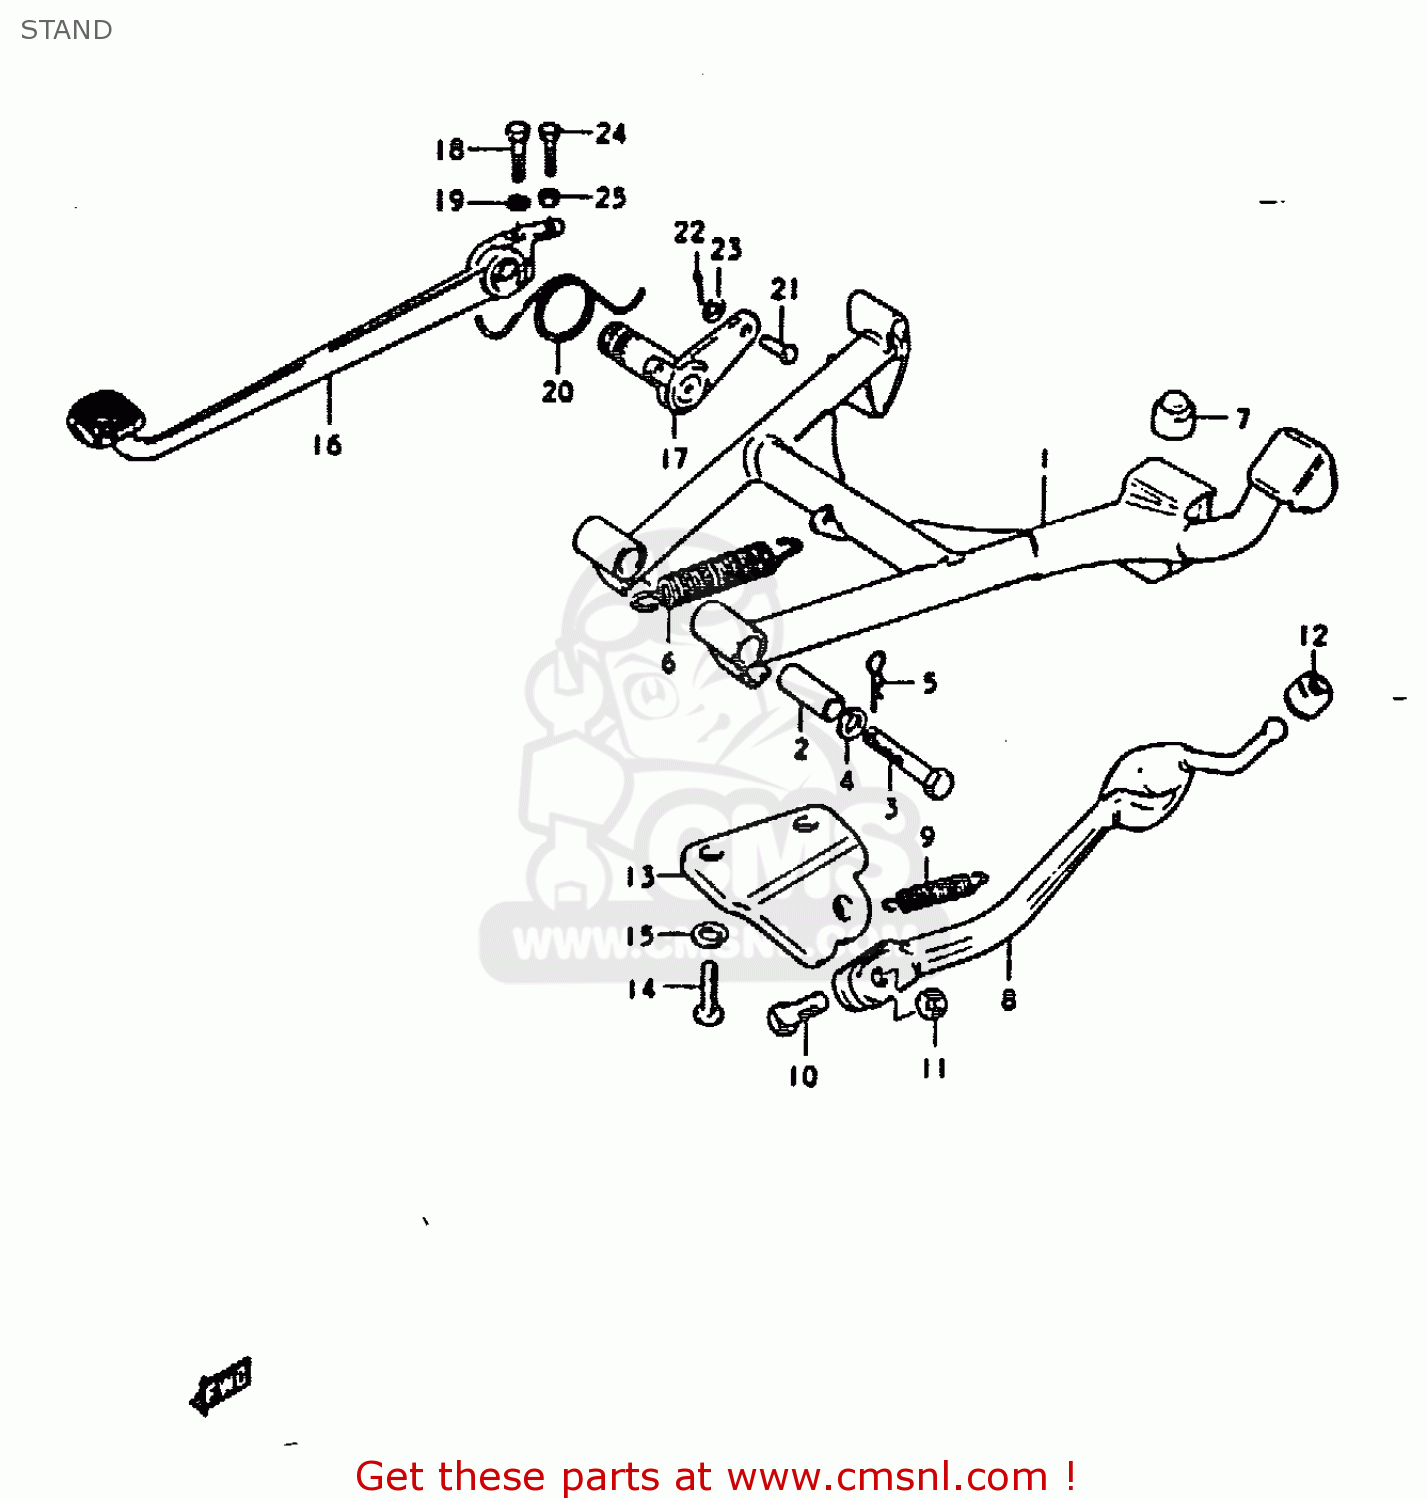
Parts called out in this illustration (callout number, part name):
1	STAND,CENTER
2	SPACER(10X16X38.8)
3	BOLT
4	LOCK WASHER
5	CLIP
6	SPRING
7	CUSHION
8	STAND,PROP
9	SPRING
10	BOLT(10X30)
11	NUT
12	CUSHION
13	BRACKET,SIDE STAND
14	BOLT
15	LOCK WASHER
16	PEDAL,BRAKE
17	ARM,BRAKE PEDAL
18	BOLT
19	LOCK WASHER
20	SPRING
21	PIN
22	PIN
23	WASHER
24	BOLT
25	NUT
